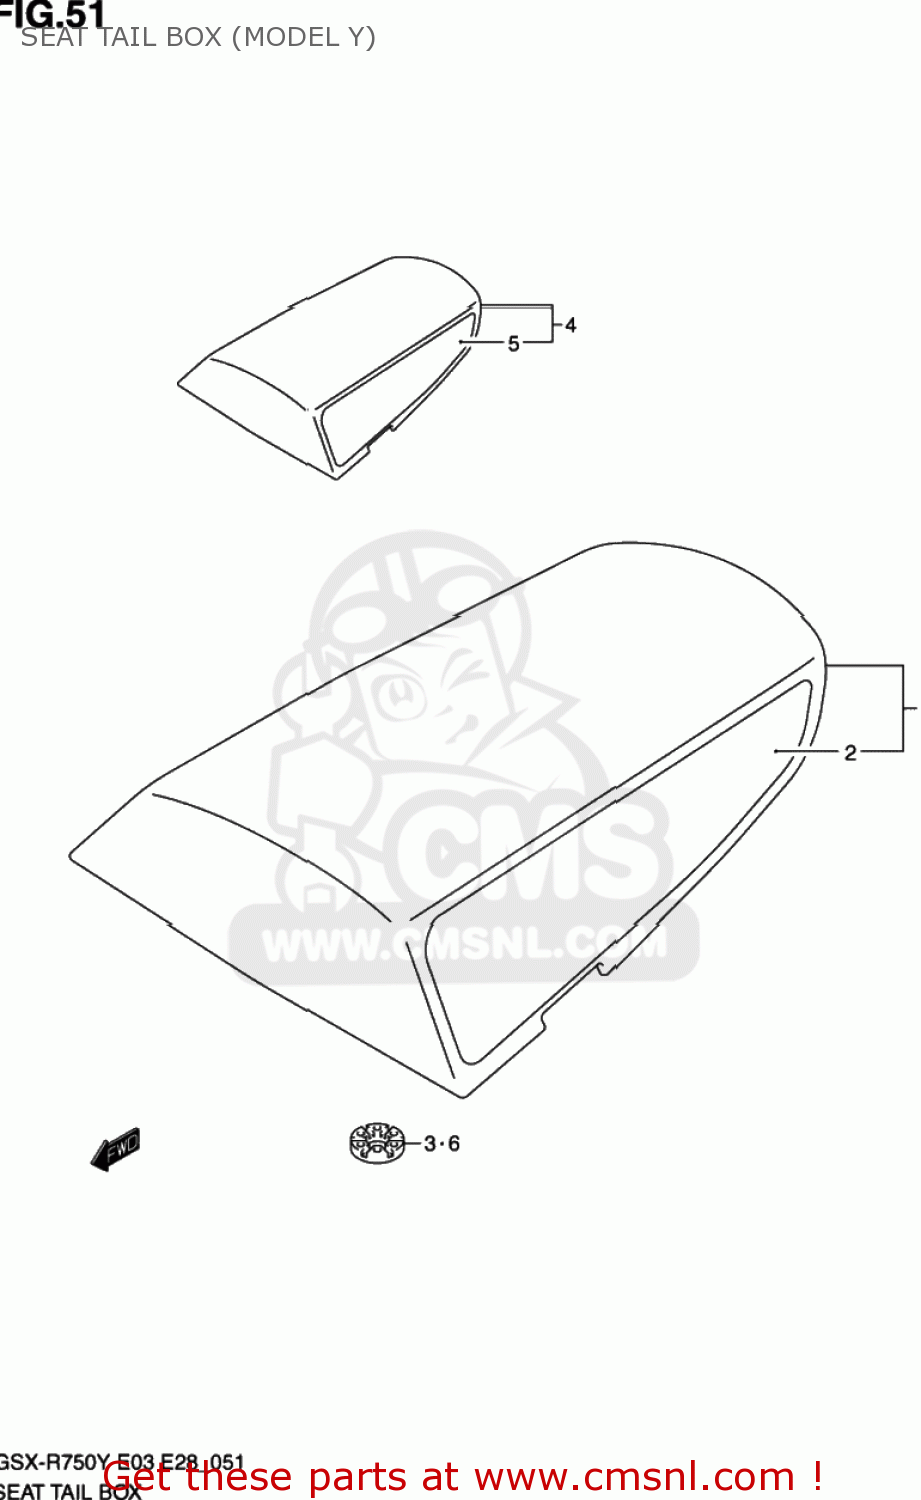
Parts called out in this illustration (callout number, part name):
1	BOX ASSY,SEAT TAIL(BLACK)
2	TAPE SET,BOX SEAT TAIL
3	CUSHION
4	BOX ASSY,SEAT TAIL(BLACK)
5	TAPE SET,BOX SEAT TAIL
6	CUSHION
